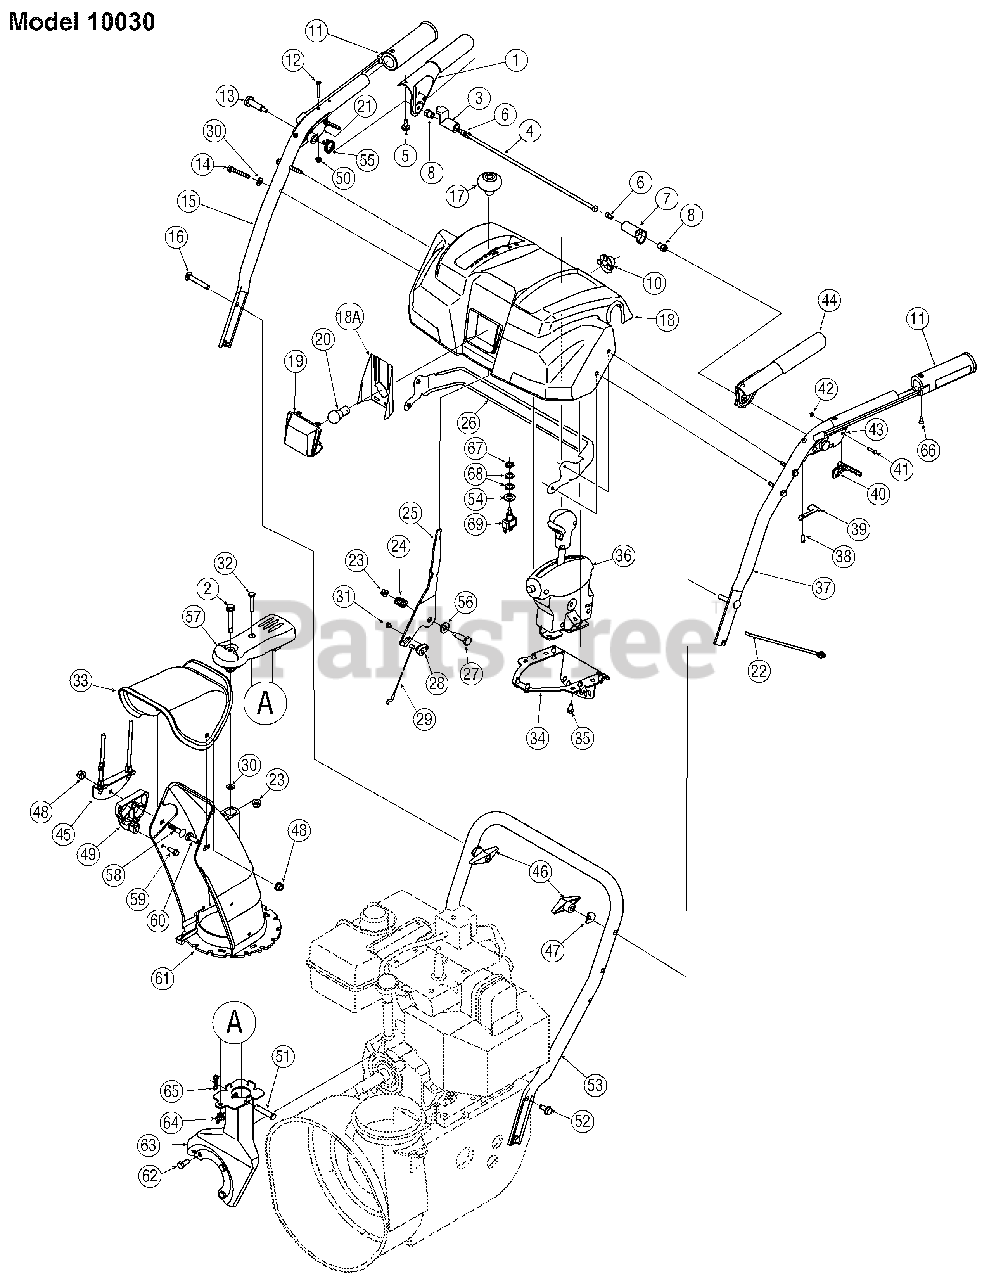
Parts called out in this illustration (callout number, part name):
1	Handle Engagement Assembly
2	Flange Shoulder Screw
3	Lock Plate
4	Pivot Rod
5	Rubber Bumper
6	Screw, 1/4-20 x.375
7	Clutch Lock Cam
8	Shoulder Nut, 1/4-20
10	Light Socket
11	Heated Handle Grip
12	Screw, #10-24 x 0.375
13	Shoulder Screw, 1/4-20 x 1.345
14	Screw, 1/4-20 x 1.750
16	Carriage Screw, 5/16-18 x 2.25
17	Shift Knob
18	Handle Panel (Includes Ref. #19)
18A	Troy Lens Label
20	Lamp
21	Handle Clutch Lock - RH
22	Cable Tie
23	Flange Lock Nut, 1/4-20
24	Compression Spring
28	Cable Barrel Holder
29	Speed Selector Cable
30	Flat Washer, .25 x .630 x .0515
31	Screw, #10-16 x .500
32	Hex Screw, 1/4-20 x 1.50
33	Upper Chute
35	Hi-Lo Screw, 1/4-15 x 0.5
36	4-Way Chute Control™ (Includes Ref.# 57)
38	Screw, #8-16 x 0.50
39	Clutch Lock Spring
40	Steering Control
43	Handle Clutch Lock - LH
44	Handle Engagement Assembly
46	Handle Knob Assembly
47	Saddle Washer
48	Flange Lock Nut, 5/16-18
49	Chute Tilt Cable Guide
50	Hex Lock Nut, #10-24
52	AB Screw, 5/16-18 x 0.75
54	Flat Washer, .474 x .879 x .064
55	Torsion Spring
56	Flat Washer
57	Joystick Pulley Cover
58	Carriage Bolt, 5/16-18 x 1.50
59	Hi-Lo Screw, 1/4-15 x .75
60	Carriage Bolt, 5/16-18 x 1.0
61	Lower Chute
62	Hex Screw, 5/16-24 x .750
65	Bow Tie Cotter Pin
66	AB Screw, #10-16 x .625
68	Toggle Switch Lock Ring
69	Toggle Switch
